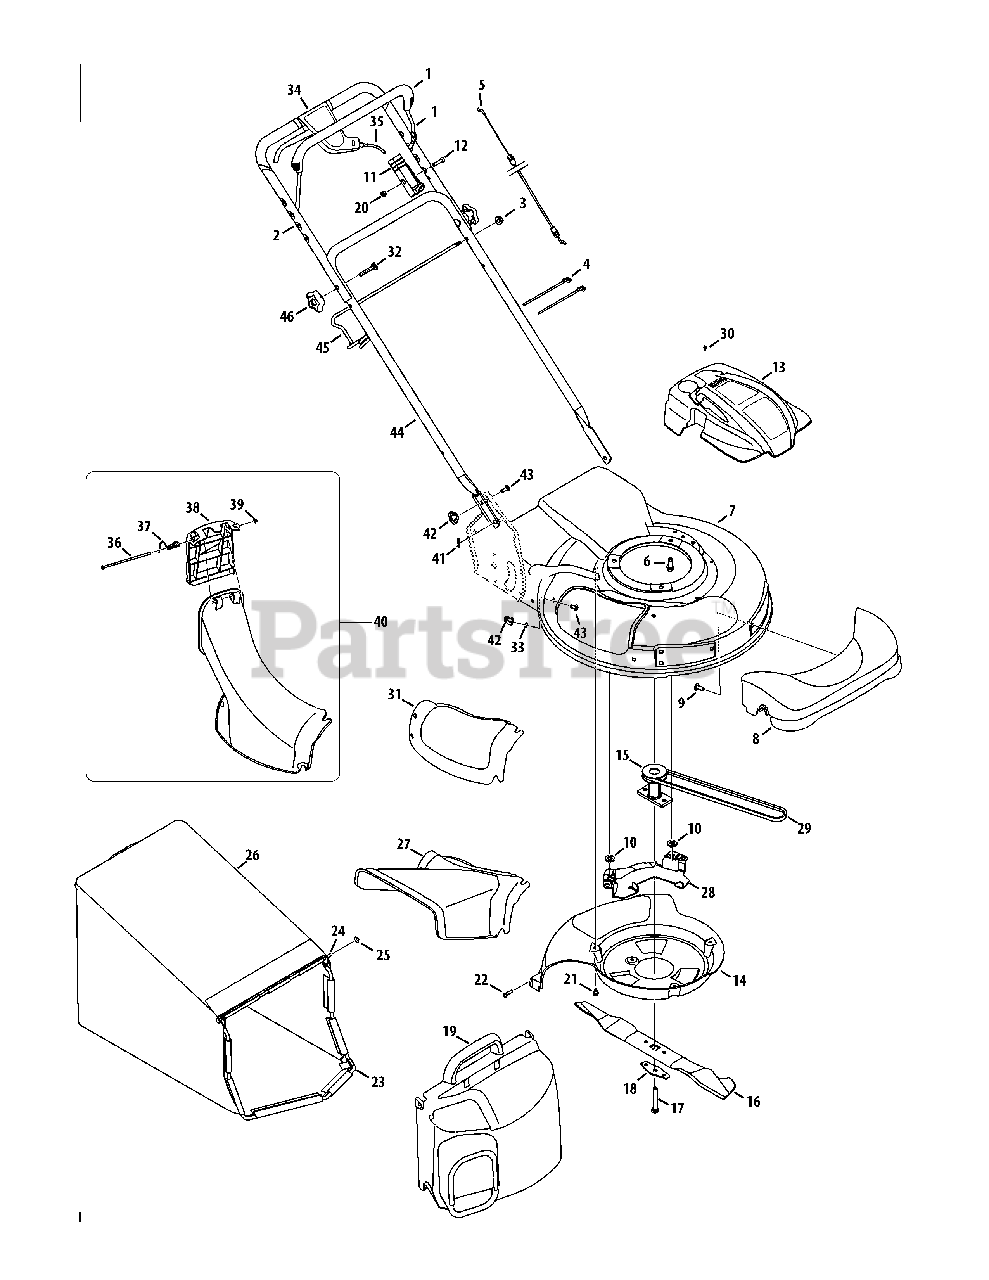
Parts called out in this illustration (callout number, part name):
1	Blade Control Assembly
3	Flange Lock Nut, 5/16-18
4	Cable Tie
5	Control Cable
6	TT Screw, 3/8-16 x 1.00
8	Front Axle Cover
9	HL Screw, 5/16-14 x .750
10	Washer, Flat, .407 x .812 x .135
11	Control Cable Mount
12	Screw, 1/4-20 x 1.50
13	Engine Shroud
14	Engine Baffle
15	Blade Adapter
16	21-inch Mulching Blade
17	HH Cap Screw, 3/8-24 x 2.50
18	Bell Blade Spacer
19	Grass Bag Cover Assembly
20	Flange Lock Nut 1/4-20
21	TT Screw 1/4-20 x .375
22	HL Screw 1/4-15 x .75
23	Grass Bag Frame
24	Grass Bag Pivot Rod
25	Cap Speed Nut
26	Grass Bag
27	Side Discharge Chute
28	Belt Keeper
30	Screw, #12-16 x 1.00
31	Mulch Cover
32	Carriage Bolt 5/16-18 x 2
34	Drive Control Assembly
35	Drive Cable
36	Chute Door Pivot Rod
37	Torsion Spring
38	Top Discharge Door Chute
40	Top Discharge Chute Assembly
41	Cotter Pin
42	Wing Nut
43	Carriage Screw 1/4-20 x .75
45	Grass Bag Support Rod
